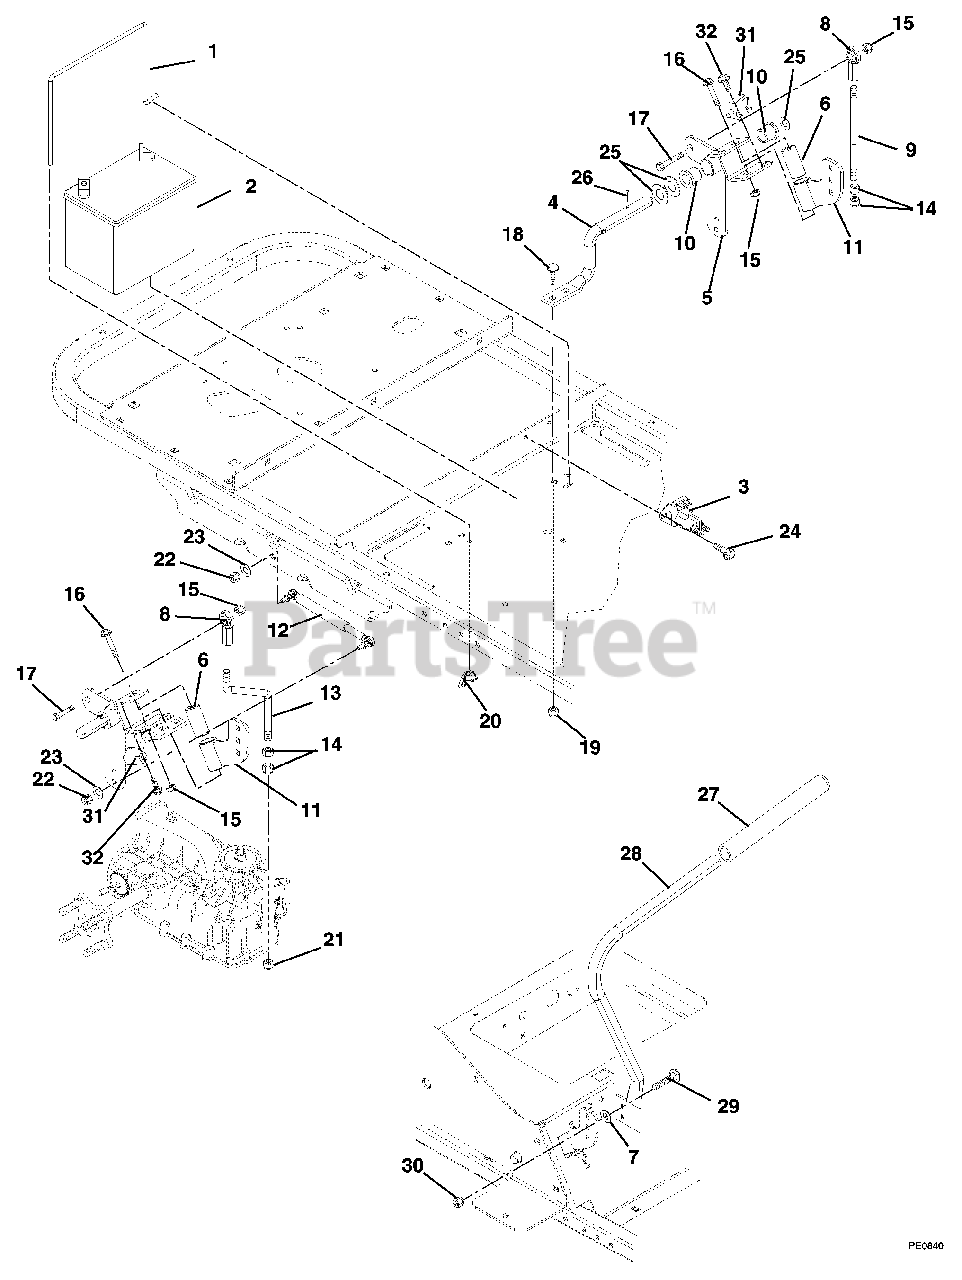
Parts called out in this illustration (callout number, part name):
1	Battery Rod
2	Battery (12 Volt, 330 CCA, 50 Min. Reserve Cap.) (034, 036, 038, 040)
3	Solenoid
4	Rod Pivot
5	Weldment, Control
7	Washer, Locking Extenal .326 x .599 x .031
8	Rod End, .50 Right Hand
9	Rod, Transaxle Left Hand
10	Bushing 1.00 x .75 x 1.00
11	Weldment, Handlebar
13	Rod, Transaxle Right Hand
14	Nut, Jam .50-20 Grade 2
15	Nut, Locking Top Flange .50-13
16	Bolt, Hex .50-13 x 3.00 Grade 5
17	Bolt, Hex .50-13 x 1.50 Grade 5
18	Bolt, Round Head Square Neck .38-16 x 1.00 Grade 5
19	Nut, Locking Top Flange .38-16
20	Nut, Locking Wing .25-20
21	Nut, Jam Nyloc .50-20 Grade 2
22	Nut, Hex M8-1.25
23	Washer, Locking .31 x .078 Regular
24	Screw, Tapping .25-20 x .37 Hex Washer Head
25	Washer, Flat Steel .754 x 1.00 x .032
26	Pin, Roll .188 x 1.13
27	Grip, Handlebar
28	Handlebar, Right Hand
28	Handlebar, Left Hand
29	Bolt, Round Head Square Neck .31-18 x .88 Grade 5
30	Nut, Locking Top Flange .31-18
31	Switch, Double Pole N.O./N.O.
32	Screw, Tapping 10-24 x .50 Hex Washer Head
